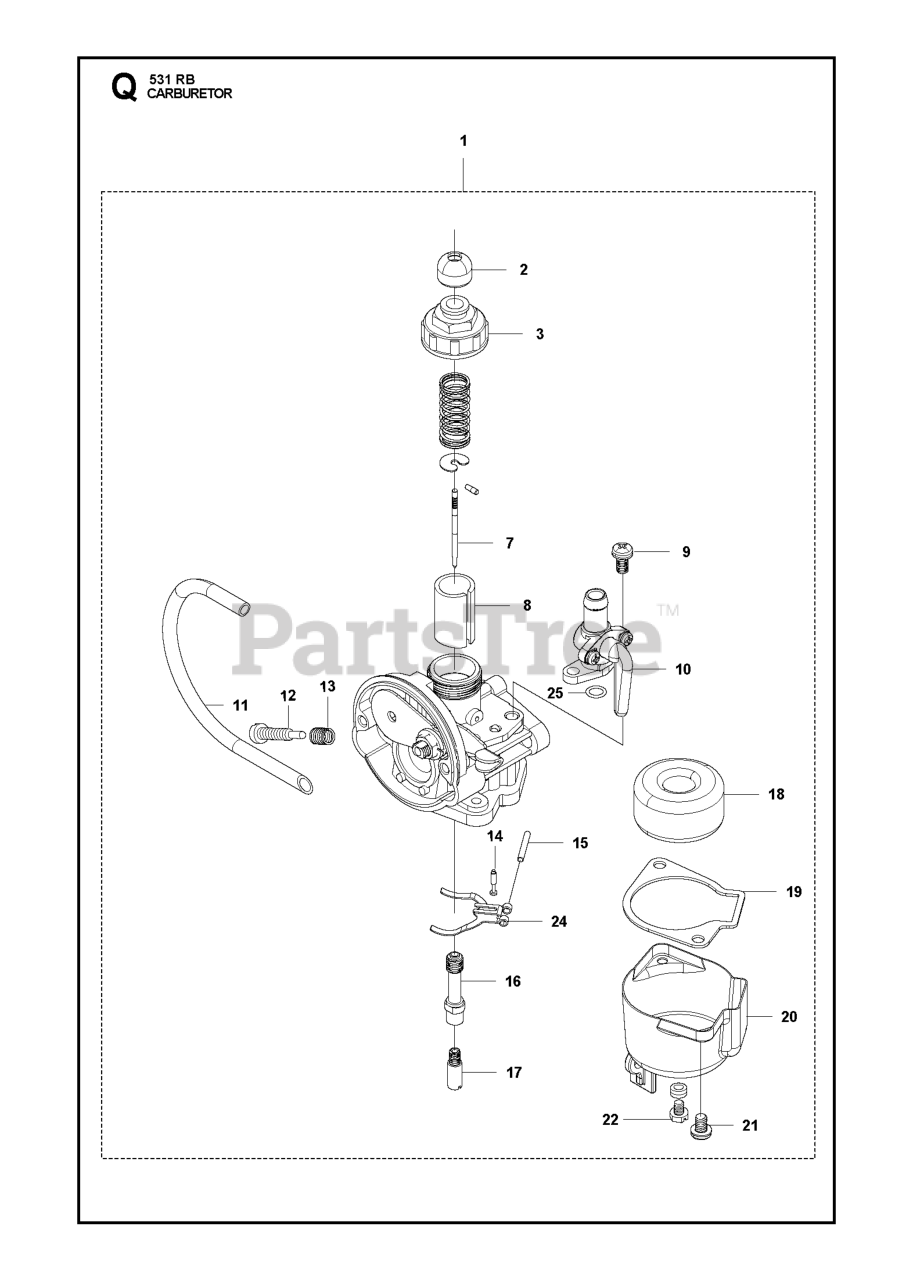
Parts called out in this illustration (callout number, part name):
8	VALVE, THROTTLE
12	SCREW.ADJUST
14	VALVE.NEEDLE
